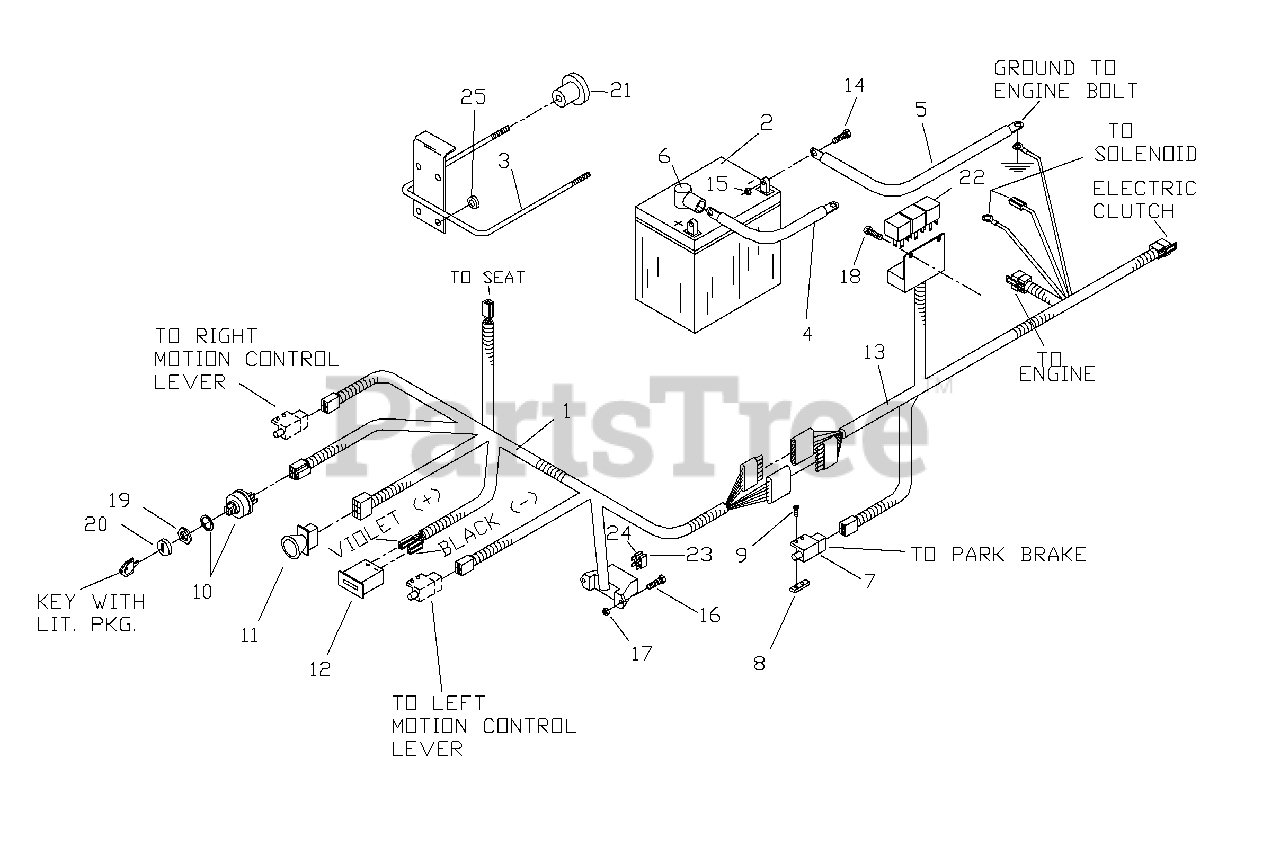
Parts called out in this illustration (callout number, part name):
1	CONSOLE HARNESS
2	12V BATTERY
3	BATTERY HOLD DOWN
4	POSITIVE CABLE
5	NEGITIVE CABLE
7	INTERLOCK SWITCH
8	TAPPED PLATE
9	#10-24 X 5/8
10	IGNITION SWITCH
11	BLADE SWITCH
12	HOUR METER
13	FRAME HARNESS
14	HCS 5/16C X 3/4
15	NUT 5/16C CTR. LOCK
16	#10-24 X 7/8 SCREW
17	#10-24 HEX NYLOC NUT
18	SELF TAPPING SCREW
19	NUT IGN. SWITCH
20	CAP, IGN. SWITCH
23	7.5 AMP 32V ATO FUSE
24	20.0 AMP 32V ATO FUSE
